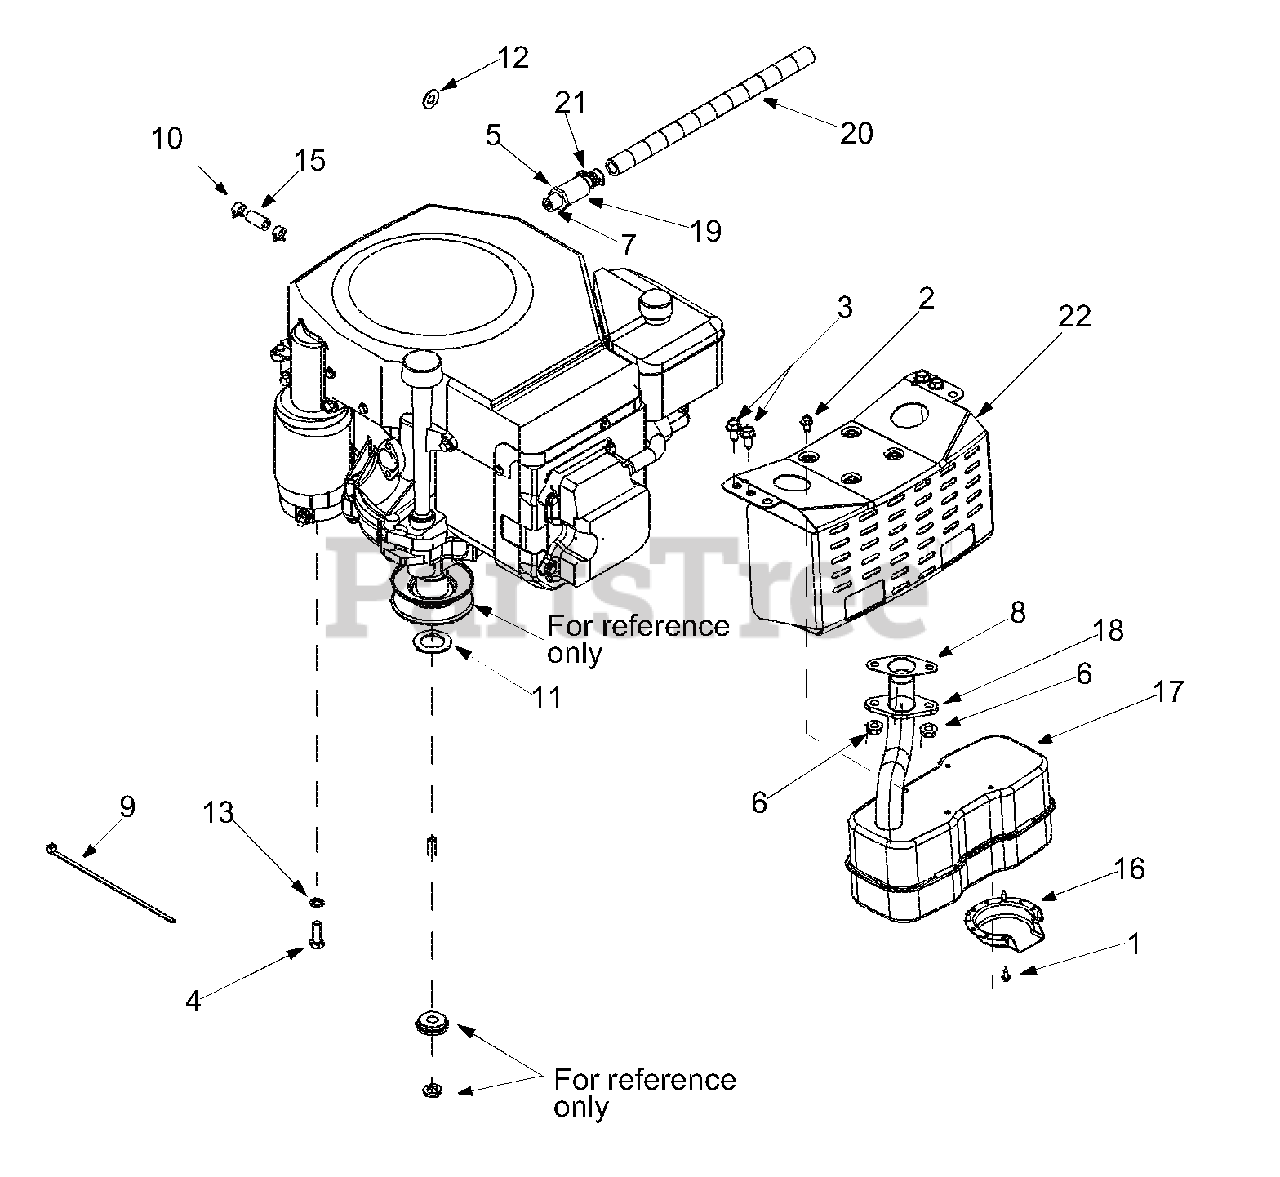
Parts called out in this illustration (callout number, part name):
1	AB Screw #8-18 x 0.5
2	TT Screw 1/4-20 x 0.5
3	AB Screw 5/16-12 x 0.75
4	Hex Screw M8
5	Hex Nut 3/8-16
6	Flange Nut M8
7	Sealant: Loctite (TM)
8	Gasket: Exhaust
9	Cable Tie
10	Hose Clamp
11	Flat Washer
12	Flat Washer
13	Lock Washer 5/16
15	Hose: Fuel Line
16	Deflector: Muffler
17	Muffler: Single Inlet
18	Exhaust Pipe
19	Oil Drain
20	Oil Drain Extension
21	Oil Drain Cap
